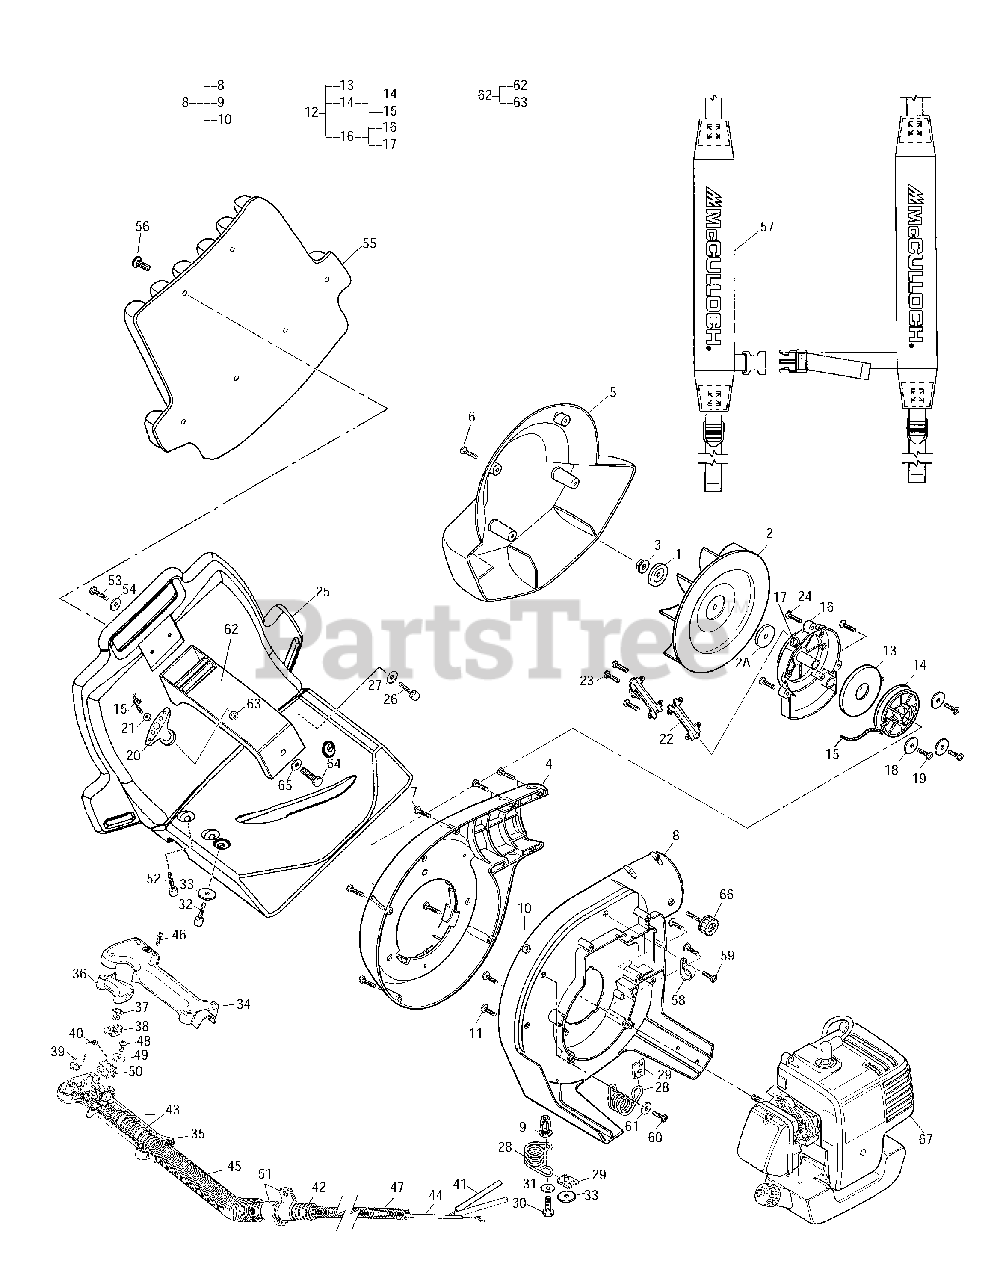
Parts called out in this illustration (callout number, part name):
1	Disc, Drive
2	Kit, Impellar, Blower
2A	Disc, Drive
3	Nut, Hx 5/16-24
4	Outer Housing
5	Cover, Air Inlet
6	Screw, 8-16 x .75 Tr Hd Plastite
7	Screw, 8-16 x .75 Tr Hd Plastite
8	Inner Housing Asy
9	Captive Nut
10	Rope Guide
11	Screw, 10-24 x .63 Sl Torx Tp
12	Starter Housing Asy
13	Spring/Starter Rewind
14	Drum Rope Asy
15	Rope, Starter 46"
16	Kit, Starter Housing
17	Rope Guide
18	Washer, .2 ID x 7/8 in. OD
19	Screw, 8-16 x .75 Tr Hd Plastite
20	Handle, Starter
21	Washer, Nylon
22	Cover, Rope
23	Screw, 8-16 x .75 Tr Hd Plastite
24	Screw, 8-16 x .75 Tr Hd Plastite
25	Frame, Back
26	Screw, Hx 1/4-20x.75
27	Washer, .275x.680x.060
28	Spring, Isolator
29	Nut, 1/4-20 Type U
30	Screw, Hx 1/4-20x.75
31	Washer, Pl .250 ID
32	Screw, Skt 1/4x20x1.0T
33	Washer, .275x.68x.06
34	Housing, Control RH
35	Housing, Control LH
36	Trigger, Throttle
37	Knob, Lock
38	Pin, Lock
39	Spring, Trigger
40	Spring, Lock
41	Wire Asy, Terminal
42	Housing, Flex
43	Clamp, Band
44	Cable, Throttle
45	Sleeve, Flex, 22mm
46	Screw, 6-19x.62Fl Hd Plast
47	Sleeve, Flex, 9mm
48	Screw, Tr 8-16x.5 Torx
49	Washer, .19 ID x .68 OD
50	Switch, Rocker
51	Clamp, Arm
52	Screw, Hx 1/4-20x.75
53	Screw, Tr 10-14x.75 Torx
54	Washer, 10 Pl
55	Cushion, Back
56	Rivet, Ribbed 14.5
57	Harness, Torso
58	Clamp, Cable 9/16
59	Screw, 8-16x.75 Tr Hd Plast
60	Screw, Tr 10-14x.75 Torx
61	Washer, .469 OD - .222 ID
62	Bracket, Isolator, Upper
63	Guide, Rope
64	Screw, Hx 1/4-20x.75
65	Washer, Pl .25 ID
66	Knob, Screw Asy
67	Powerhead Asy
